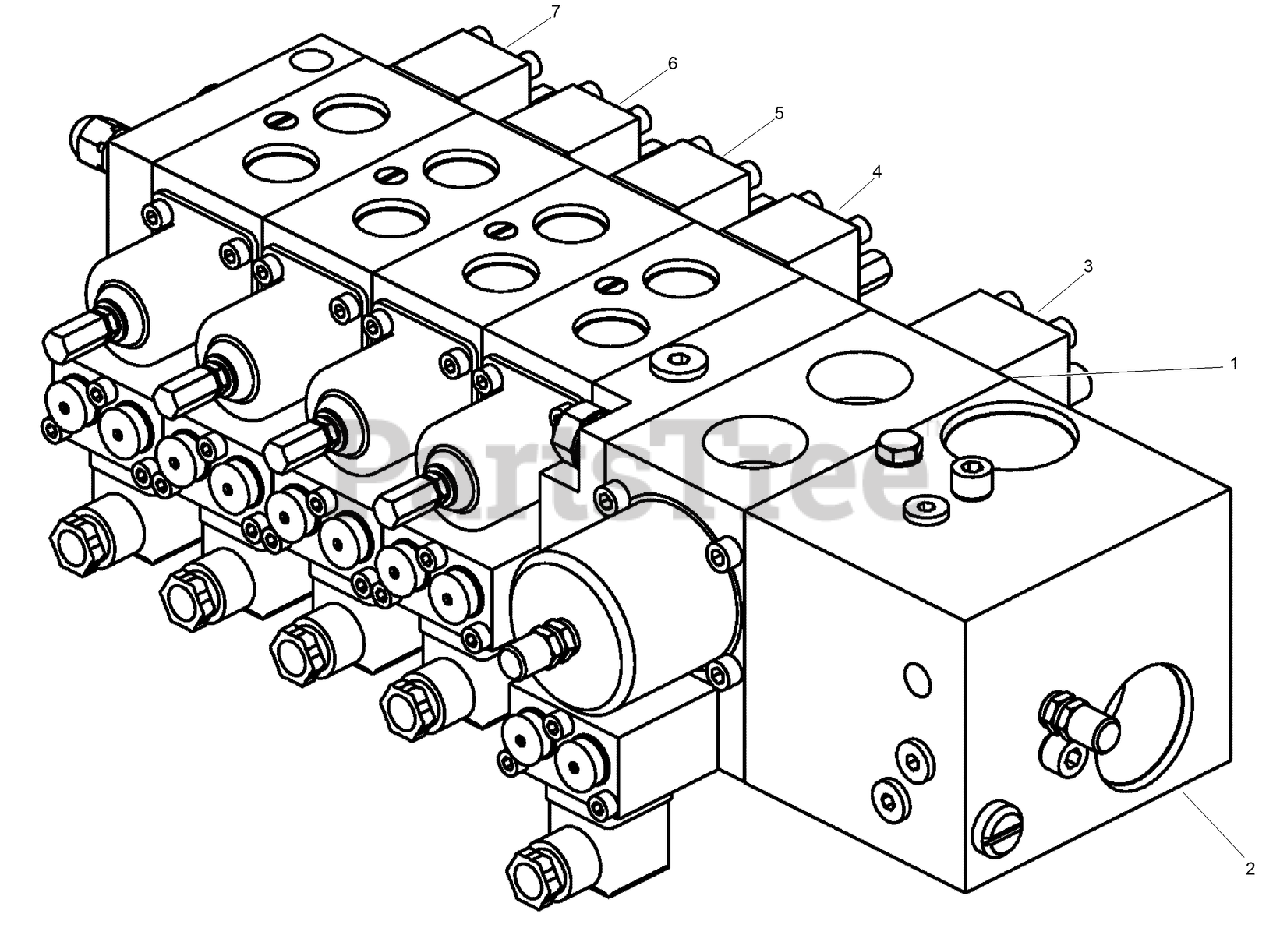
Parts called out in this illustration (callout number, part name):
1	PORT - Tank
2	PORT - Pressure
3	SECTION - Carriage
4	SECTION - Fan
5	SECTION - Left Track
6	SECTION - Right Track
7	SECTION - Auxiliary
